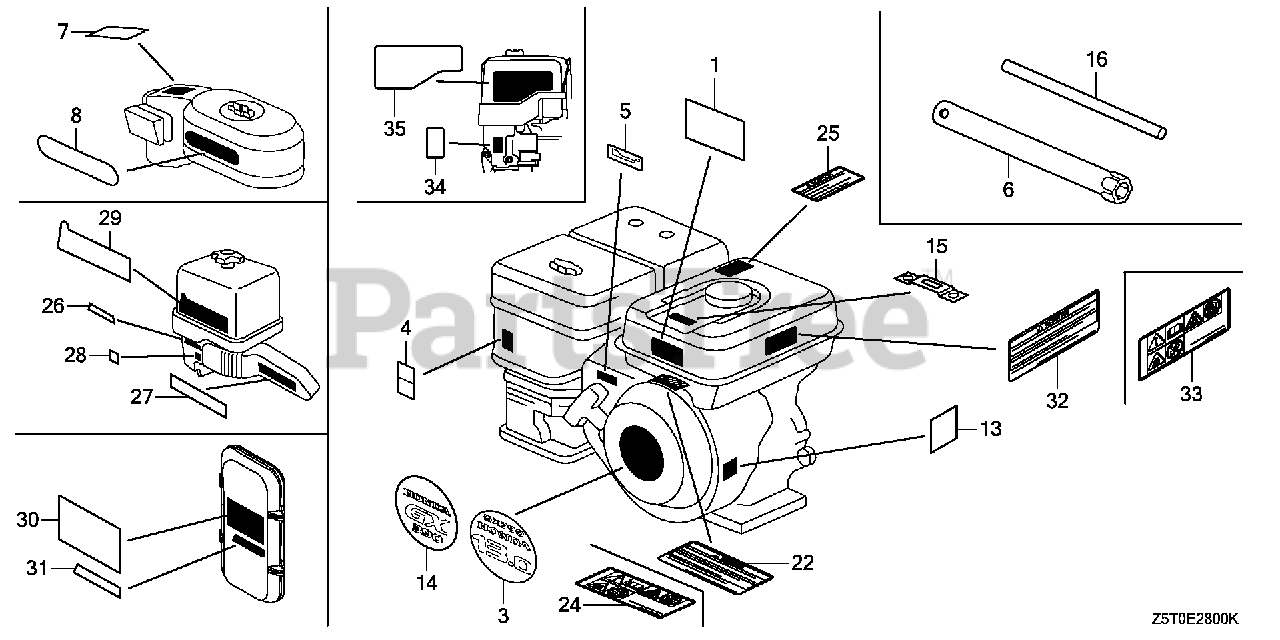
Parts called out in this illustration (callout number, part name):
26	MARK, CHOKE
27	MARK (HONDA)
28	MARK, FUEL
29	MARK, SALES POINT
33	MARK, OPERATOR CAUTION (PICTOGRAPH)
